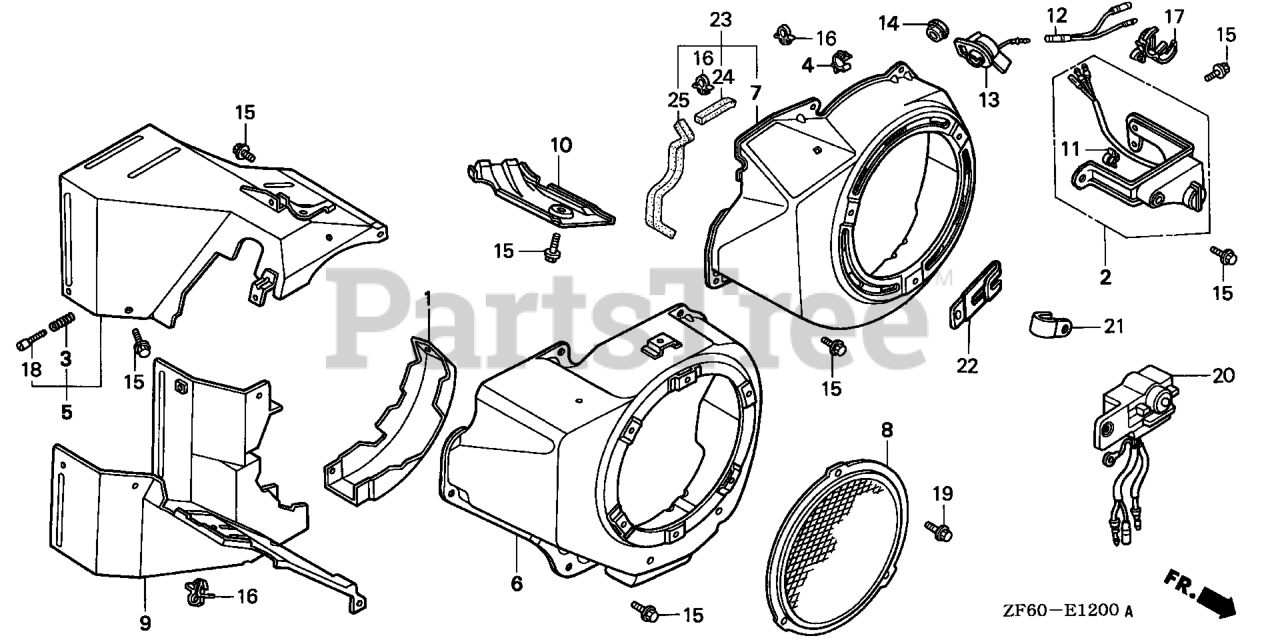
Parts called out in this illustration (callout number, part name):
2	ALERT UNIT, OIL
4	CLIP, TUBE
7	COVER, FAN *R280* (POWER RED)
11	CLIP, IGNITION WIRE (8MM)
12	SUB-HARNESS
13	SWITCH ASSY., ENGINE STOP Use from Engine SN 2092216 to 2359126.
13	SWITCH ASSY., ENGINE STOP
14	GROMMET, DRAIN HOLE
15	BOLT, FLANGE (6X12) (CT200)
17	CLIP, WIRE HARNESS
